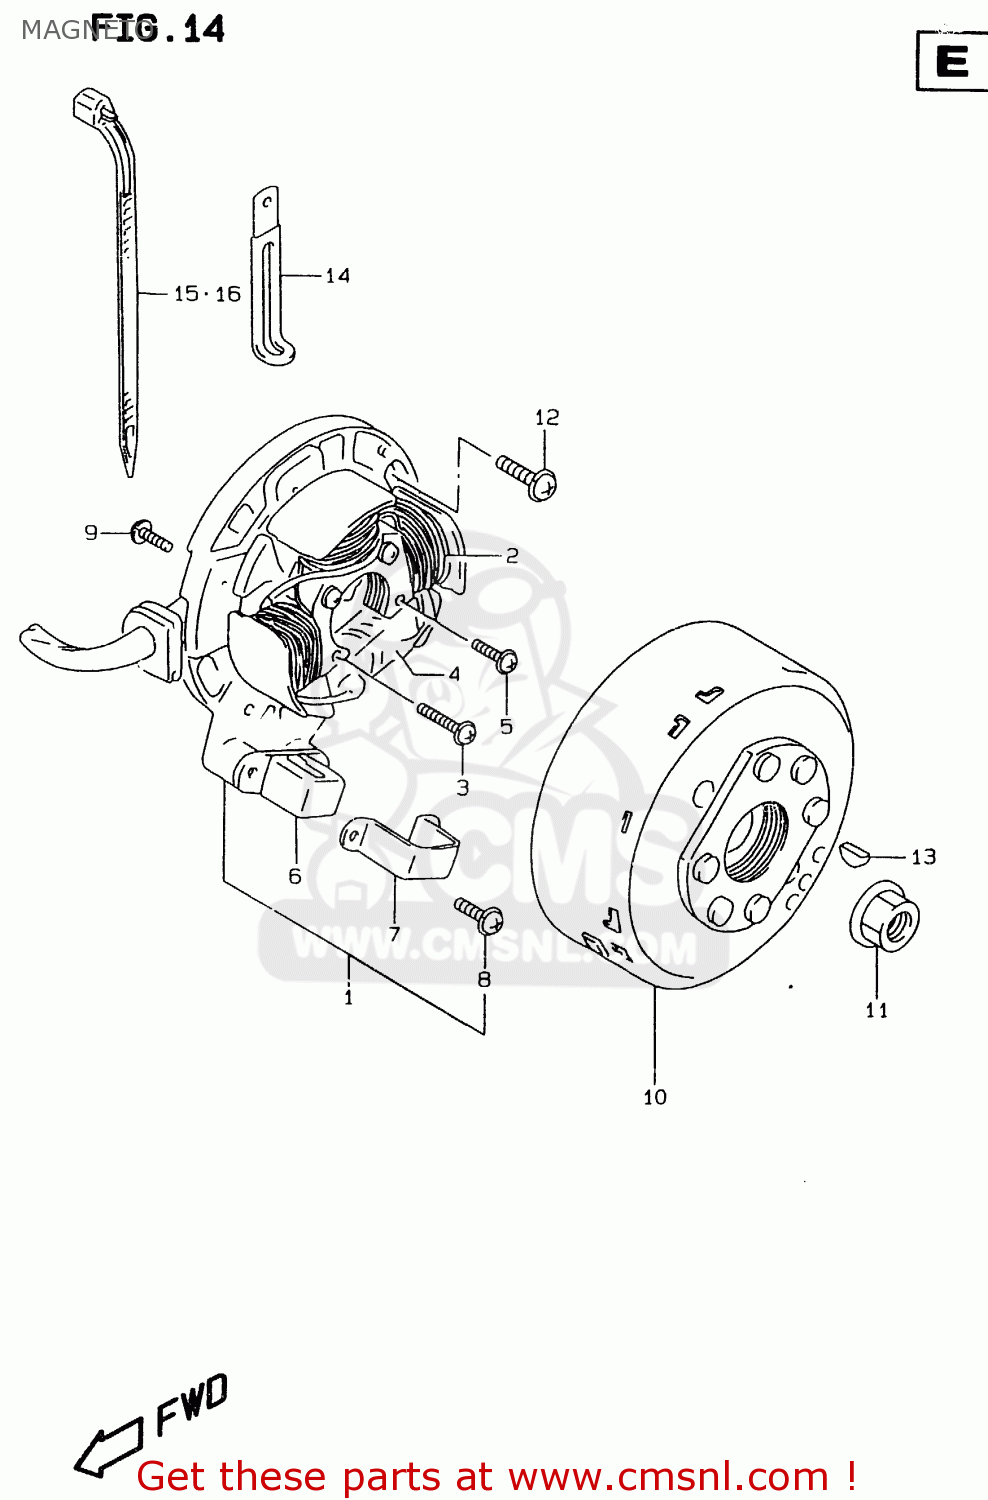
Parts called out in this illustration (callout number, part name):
1	STARTER ASSY
2	COIL,LIGHTING
3	SCREW
4	COIL,PRIMARY
5	SCREW
6	COIL,PULSER
7	HOLDER,PICK UP COIL
8	SCREW
9	SCREW
10	ROTOR ASSY
11	NUT
12	SCREW
13	KEY
14	CLAMP(L:65)
15	CLAMP(L:125)
16	CLAMP(L:235)
